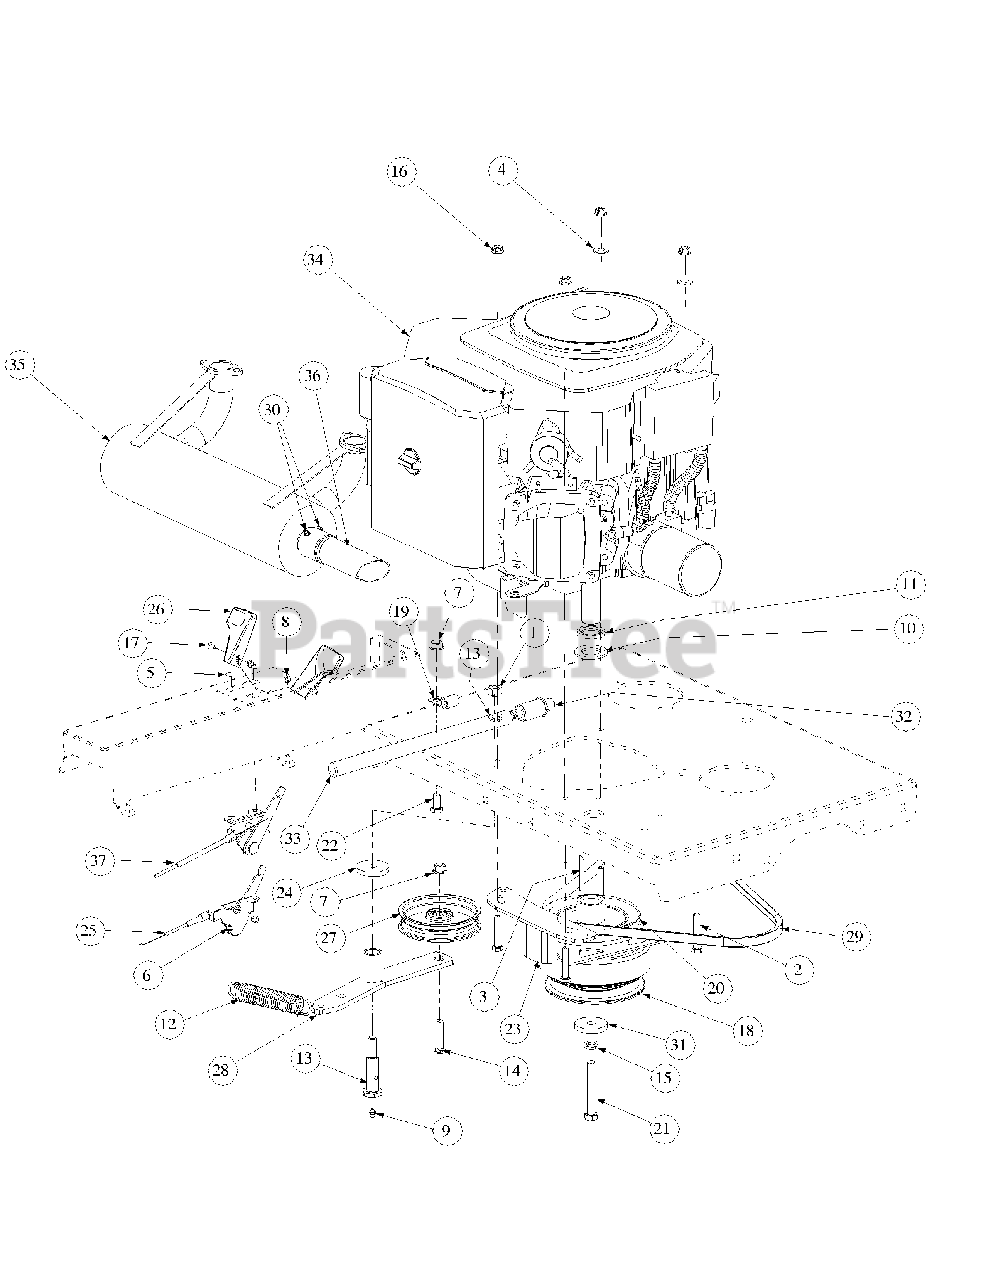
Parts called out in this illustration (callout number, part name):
1	Hex Nut, 7/16-14
2	HHCS, 5/16-18, 1-3/4
3	Key, 1/4 x 1/4 x 2.75
4	Flat Washer, 5/16
5	Round Hd. Machine Screw, 10-32 x 3/4
6	Lock Nut, Nylon Insert, 10-32
7	Flange Lock, Hex Nut, 3/8-16
8	Nut Washer, W/Star, 8-32
9	Grease Fitting, 1/4-28 x 3/16
10	Flat Washer
11	Engine Spacer
12	Extension Spring, 1.0 OD x 5.00
13	Shoulder Screw, 7/16-14
14	Hex Carriage Screw, 3/8-16, 1.75
15	Lock Washer, 7/16
16	Hexflange Lock Nut, 5/16-18
17	Machine Screw, 8-32, .375
18	Electric Clutch
19	Clip, Heat Shield Cable
20	Transmission Drive Pulley
21	Capscrew, 7/16-20 x 3.00
22	Hex Cap Screw, 3/8-16, .750
23	Retainer Clutch Assembly, Ogura
24	Flat Washer, 7/16 ID x 1.75 OD x .25
25	Throttle, Control Cable, 45.0
26	Control Throttle Knob
27	Flat Pulley with Flanges
28	Engine Idler Arm Assembly
28	Bearing
29	V Belt, A Section x 47.3
29	Belt: To be used with new sub-frame
30	Tube Clamp, 1.375
31	Flat Washer, 7/16 IDx 1.750 OD x .250T
33	Oil Drain Hose
34	23HP Kohler Engine
35	23HP Kohler Exhaust
36	Muffler Accessory Exhaust Tube
37	Choke, Control Cable, 38.0
